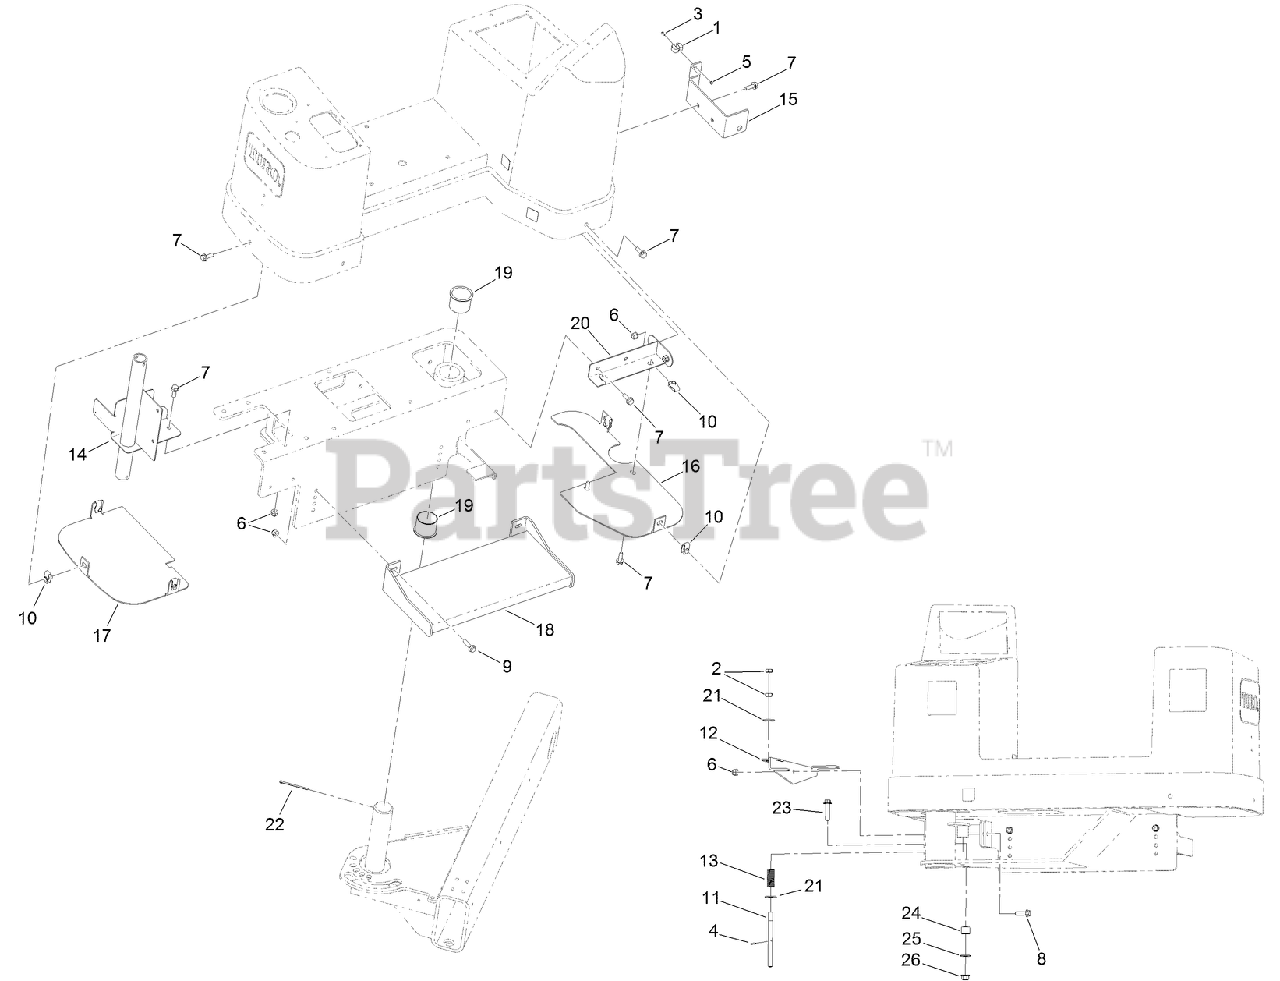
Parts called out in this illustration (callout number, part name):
1	CLIP-SPRING
2	NUT-JAM
3	SCREW-PRH
4	PIN-COTTER
5	NUT-KEPS
6	NUT-LOCK, NI
7	SCREW-HHF
8	SCREW-HHF
9	SCREW-HHF
11	ROD-SWING, SEAT
12	ARM-ADJUSTMENT, SEAT
13	SPRING-PIVOT LOCK, SEAT
14	MOUNT-UMBRELLA
15	PLATE-RETAINING, CORD
16	PLATE-GUARD, SPLASH
17	PLATE-GUARD, SPLASH
19	BEARING-FLANGED
20	SUPPORT-SHROUD, LEFT
21	WASHER-FLAT
22	PIN-COTTER
23	SCREW-HHF
24	SPACER
25	WASHER-FLAT
26	NUT-LOCK, HHF
